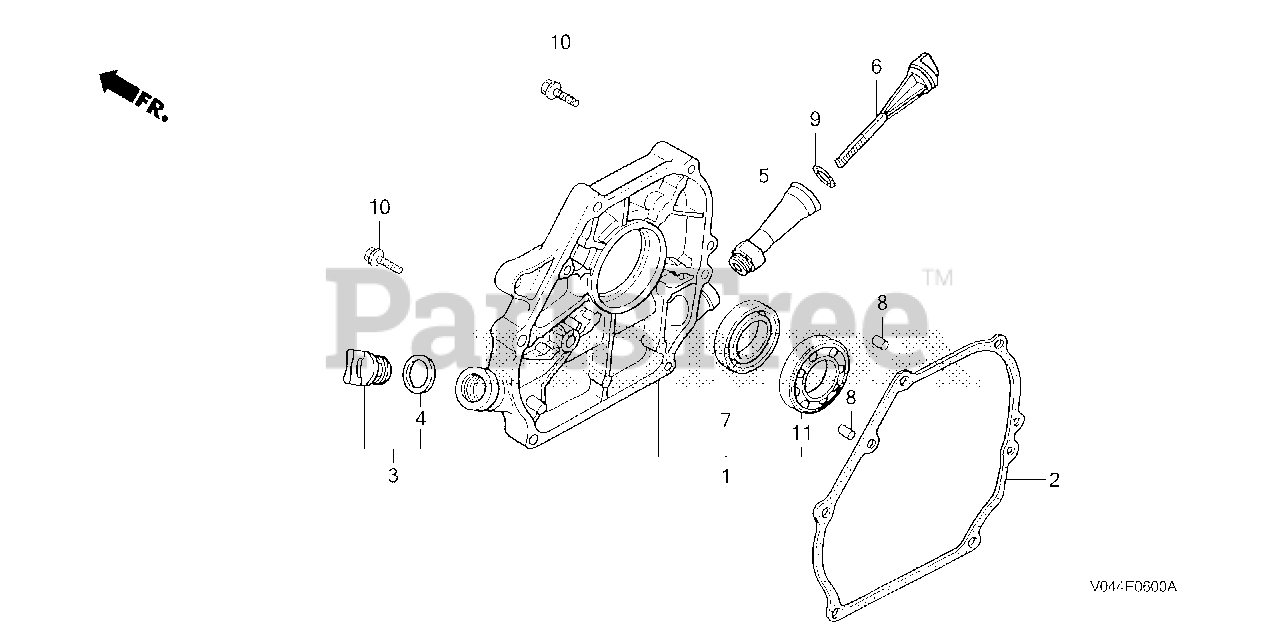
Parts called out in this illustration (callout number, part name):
1	COVER ASSY., CRANKCASE
2	GASKET, CASE COVER (NON-ASBESTOS)
2	GASKET, CASE COVER
3	CAP ASSY., OIL FILLER
4	GASKET, OIL FILLER CAP
5	PIPE, OIL FILLER
6	DIPSTICK, OIL
7	OIL SEAL (25X41X6) (NOK)
8	PIN, DOWEL (8X14)
9	O-RING (23X2.8)
10	BOLT, FLANGE (8X32)
11	BEARING, RADIAL BALL (6205)
